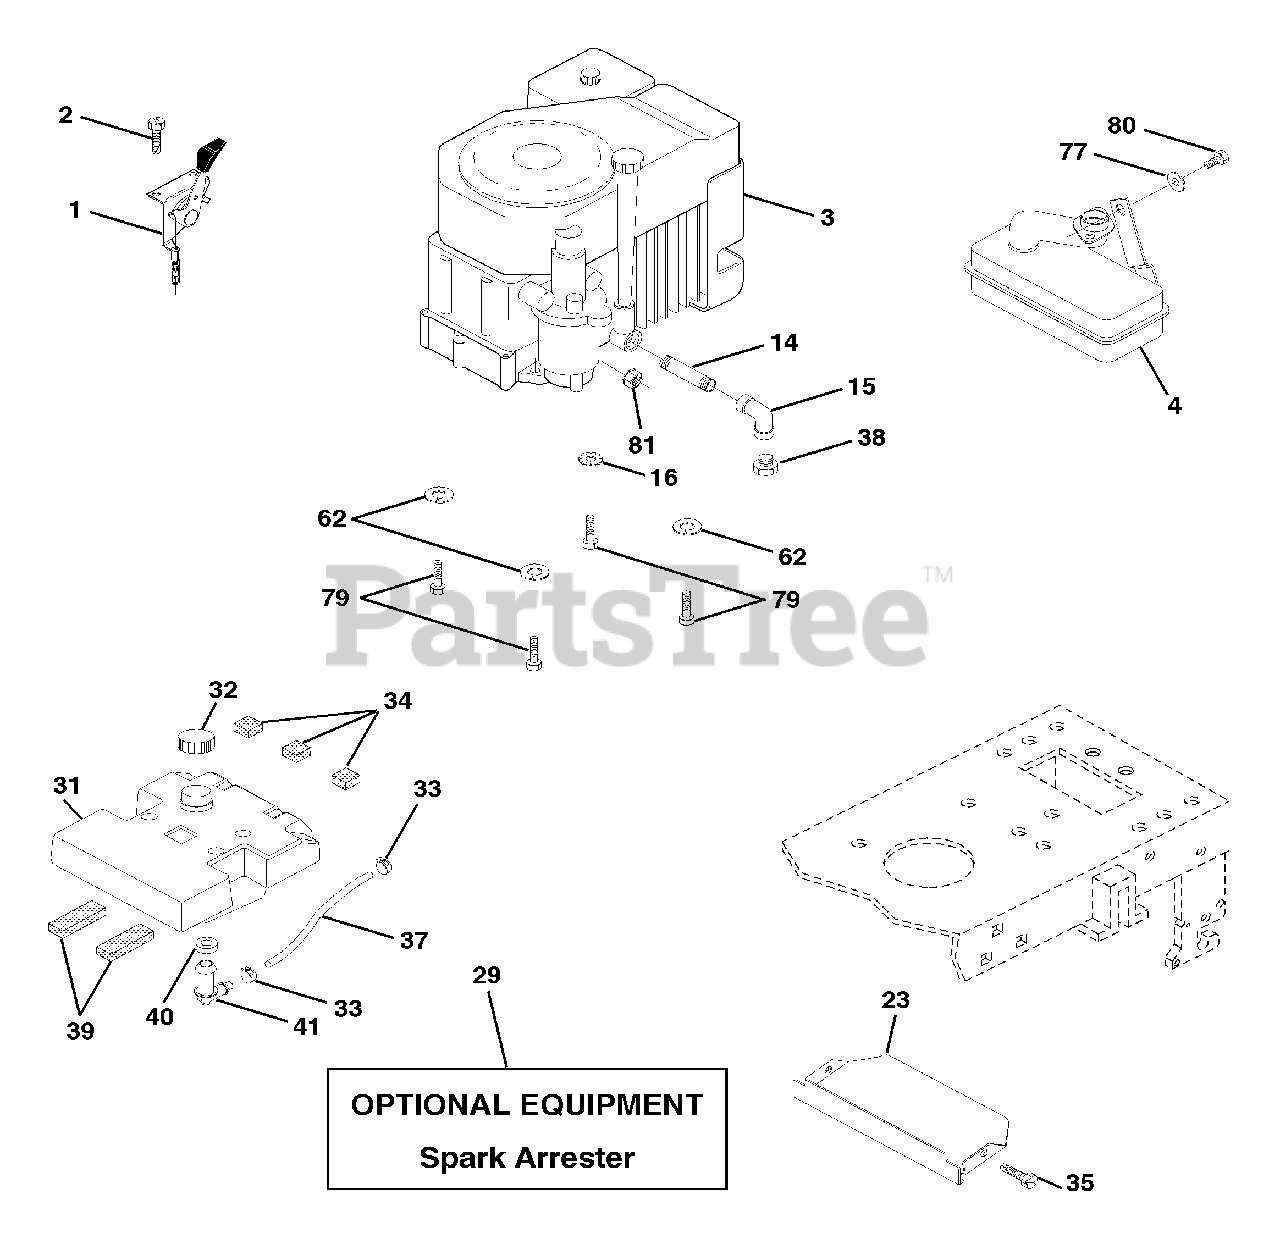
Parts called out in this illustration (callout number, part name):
1	Control Th/ch 27. LH. Flag Dom.
2	Screw Hex Thd Cut 1/4-20x5/8 T
4	Muffler LT Kohler 12.5/15HP
14	Nipple Pipe 3/8 Npt X 3-1/2
15	Elbow Std 90 Degree 3/8-18 Npt
16	Washer Lock Ext Tooth 5/16
23	Shield Heat
29	Kit Spark Arrestor (Flat Scrn)
31	Tank Fuel 3.5 STLT W/O Sensor
32	Cap Asm Fuel W/sym Vented
33	Clamp Hose Black
34	Pad Spacer
35	Screw
37	Line Fuel 7.5"
38	Plug Oil Drain
39	Pad Idler 1.75 x .75 x .06
40	Bushing
41	Stem Tank Fuel
62	Washer Lock Hvy Hlcl Spr 5/16
77	Washer 5/16 x 3/4 x 16 Ga.
79	Bolt Hex
80	Bolt Hex Hd. 5/16-18 unc x 1/2
81	Nut Flange 1/4-20 Starter Nut
